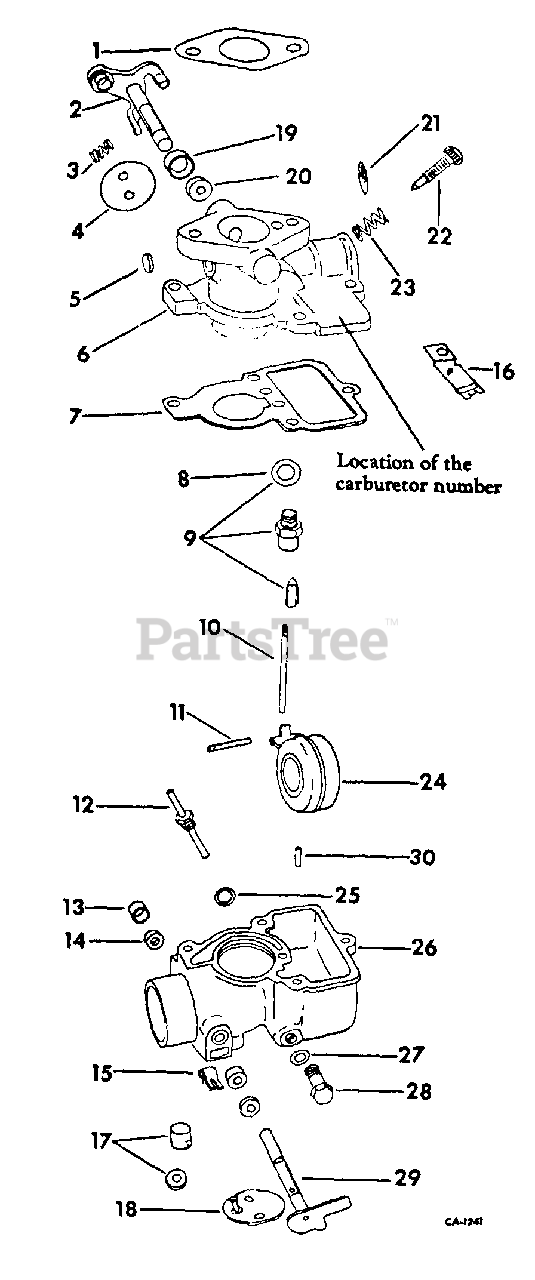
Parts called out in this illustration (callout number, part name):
1	GASKET, CARBURETOR
2	LEVER AND SHAFT ASSY, THROTTLE
3	SPRING, IDLE SET SCREW RETAINER
4	BUTTERFLY, THROTTLE
5	PLUG, THROTTLE BODY EXPANSION
6	BODY ASSY, THROTTLE
7	GASKET, FUEL BOWL
8	GASKET, FLOAT NEEDLE VALVE CAGE
9	CAGE ASSY, FLOAT NEEDLE VALVE
11	PIVOT FLOAT LEVER
12	NOZZLE, DISCHARGE
12	NOZZLE ASSY, DISCHARGE
13	RETAINER, CHOKE VALVE SHAFT DUST SEAL
13	RETAINER, STARTING SHUTTER SHAFT DUST
14	SEAL, BUTTERFLY SHAFT DUST
15	SPRING, STARTING SHUTTER FRICTION
16	NOT USED IN THIS APPLICATION
17	PACKAGE, DRIP HOLE FILLER REPLACEMENT
18	SHUTTER ASSY, STARTING
19	RETAINER BUTTERFLY SHAFT DUST SEAL
20	SEAL, STARTING SHUTTER SHAFT DUST
21	SCREEN, STRAINER
22	SCREW, IDLE ADJUSTING
23	SPRING, IDLE ADJUSTING SCREW RETAINER
24	FLOAT AND LEVER ASSY
25	GASKET, DISCHARGE NOZZLE
26	BOWL ASSY, FUEL
26	BOWL ASSY FUEL
27	GASKET, MAIN METERING JET
28	JET, MAIN METERING
28	JET ASSY, MAIN METERING
29	SHAFT, CHOKE VALVE
30	BLEED, MAIN AIR
